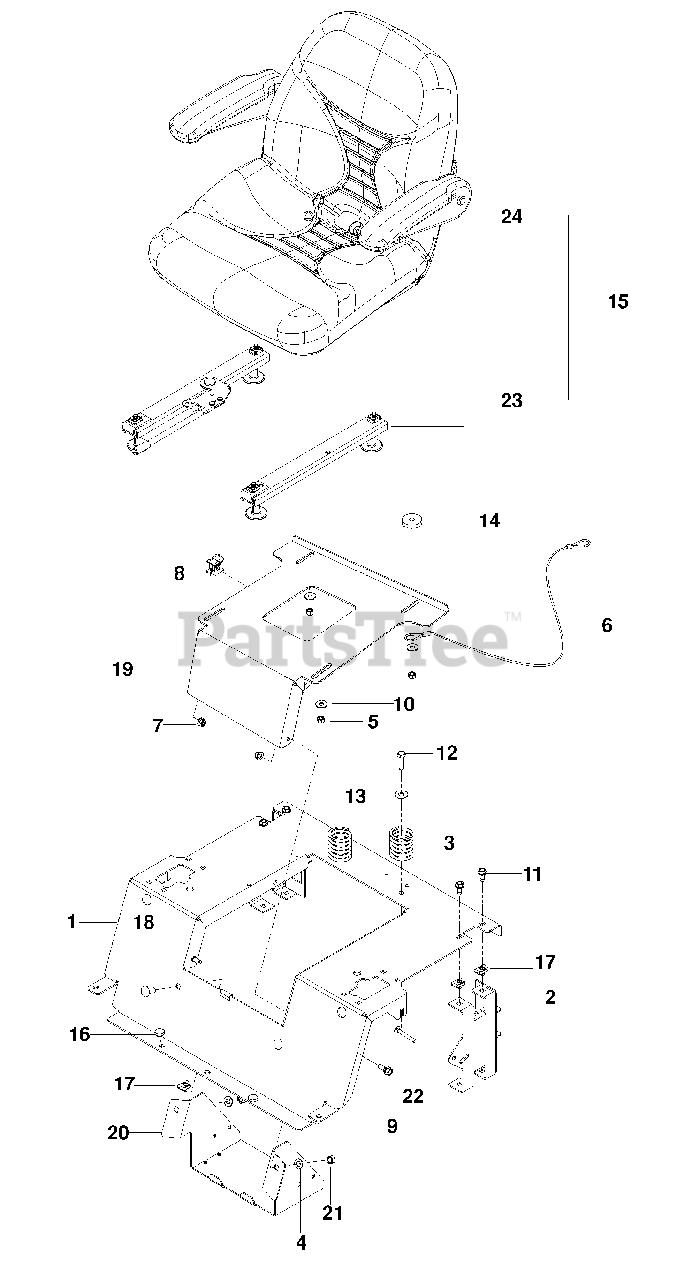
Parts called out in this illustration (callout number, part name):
1	Support, Seat Org
2	Support, Rear Seat Blk
3	Spring, Seat
4	Washer 3/8 Sae Flat
5	Nut 5/16-18 Hex Nyloc
6	Lanyard, Seat
7	Nut 5/16-18 Flange Nyloc
8	Switch, Seat
9	Bolt 5/16-18 Hex Hd Shldr
10	Washer 5/16 Std Flat
11	Bolt 5/16-18 X 3/4 Thd Frm
12	Hcs 3/8-16 X 1 1/4
13	Washer 3/8 Flat Std
14	Washer, Nylon
15	Seat
16	Grommet, Bumper
17	Retainer, U Type
18	Rhsnb 3/8-16 X 1
19	Pan, Seat Org
20	Box, Battery
21	Nut 3/8-16 Hex Nyloc
22	Rhsnb 5/16-18 X 2 1/2
23	Seat Rail Assy
24	Arm Rest Rt
25	Arm Rest Lt
